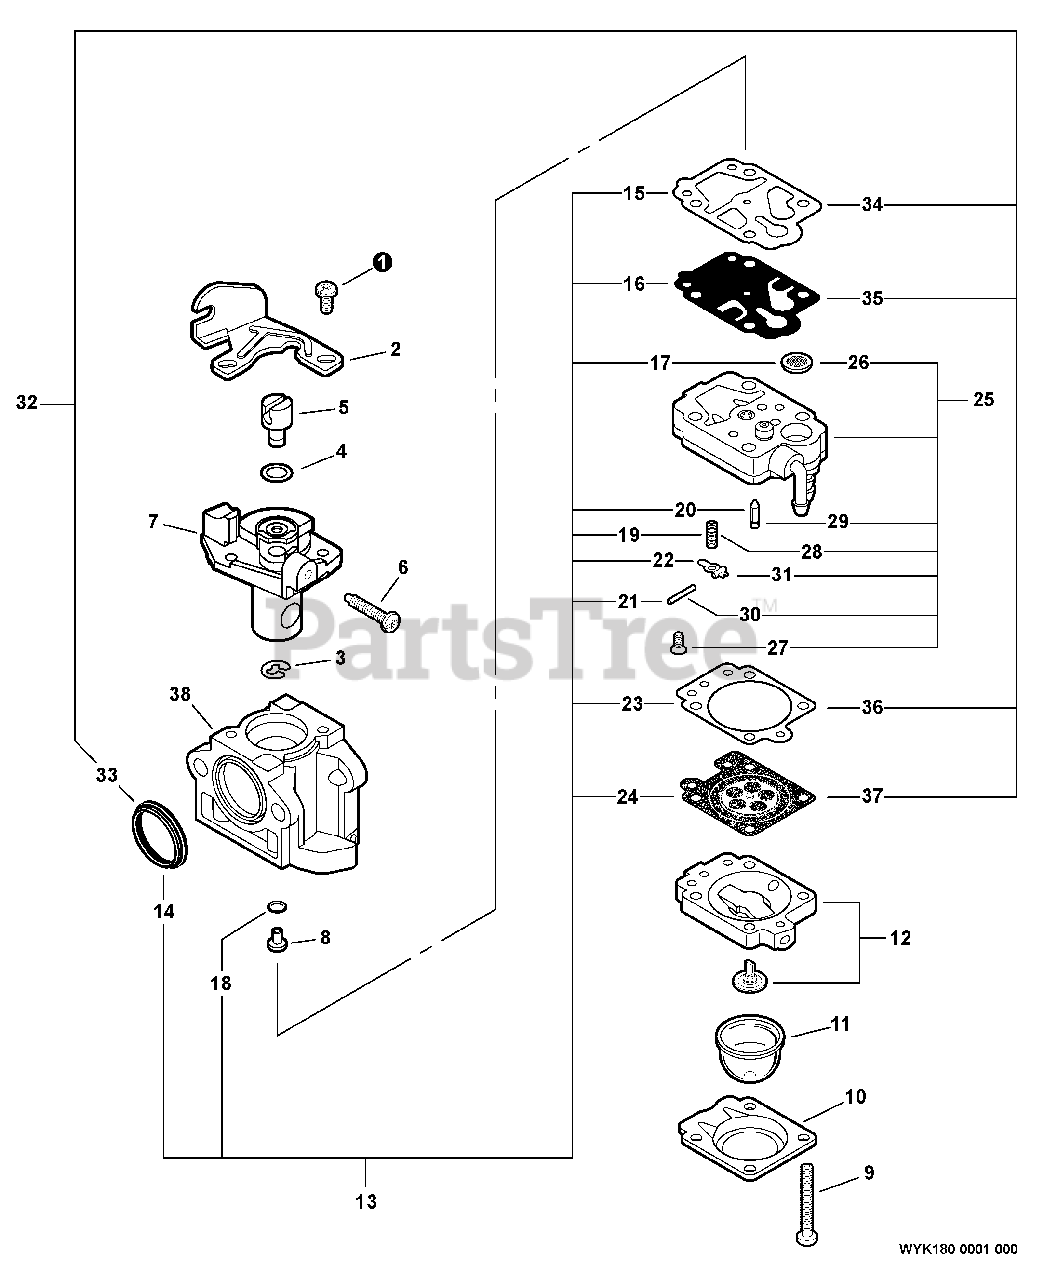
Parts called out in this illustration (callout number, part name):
2	BRACKET, CABLE
3	RING, RETAINING
6	SCREW, IDLE ADJUST
7	THROTTLE VALVE ASSY
9	SCREW, PUMP COVER
10	RETAINER, PURGE BULB
11	BULB, PURGE
12	PURGE BASE ASSY
13	REPAIR KIT
14	SEAL
15	GASKET, PUMP
16	DIAPHRAGM, PUMP
17	STRAINER
19	SPRING, METERING LEVER
20	VALVE, INLET NEEDLE
21	PIN, METERING LEVER
22	LEVER, METERING
23	GASKET, DIAPHRAGM
24	DIAPHRAGM, METERING
25	PUMP BODY ASSY
26	STRAINER
27	SCREW, METERING LEVER PIN
28	SPRING, METERING LEVER
29	VALVE, INLET NEEDLE
30	PIN, METERING LEVER
31	LEVER, METERING
32	DIAPHRAGM/GASKET KIT
33	SEAL
34	GASKET, PUMP
35	DIAPHRAGM, PUMP
36	GASKET, DIAPHRAGM
37	DIAPHRAGM, METERING
38	BODY, CARBURETOR
